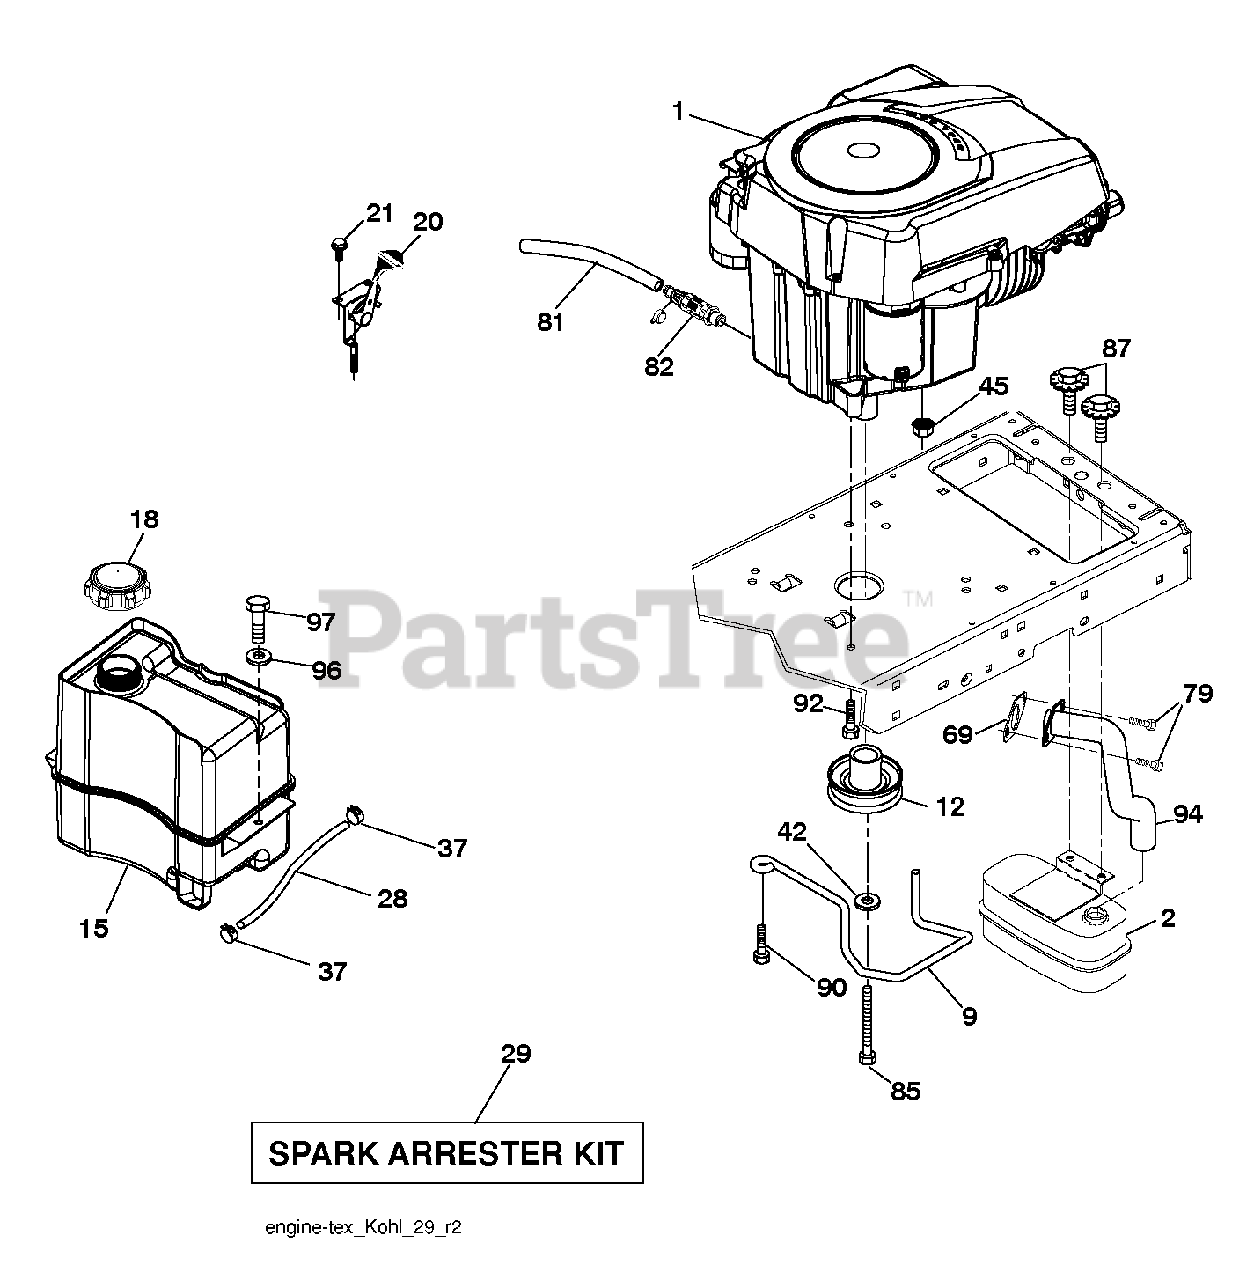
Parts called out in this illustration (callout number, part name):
1	Husqvarna TBD
2	MUFFLER.SINGLE.CYL.KOHL/B&S
9	KEEPER.BELT.ENGINE.4.2
12	PULLEY ENGINE
15	TANK.ASM.FUEL.FR.2.5GA.
18	CAP.2.25'.VENTED.TETHER .EPA
20	CONTROL.TH/CK.COBRA.KO
21	SCREW.#10 X 0.750.BOS
28	LINE.FUEL.20"FRONT.EMI
29	KIT.SPARK ARRESTOR 794945 B&S
37	HOSE CLAMP
42	LOCKWASHER
45	NUT
69	GASKET.EXHAUST.KOHLER
79	SCREW.SOCKET HD.5/16-1
81	TUBE, DRAIN OIL ASM.
82	VALUE.OIL.DRAIN
85	BOLT HEX 7/16-20X4-1/4"
87	Bolt, 5/16-18 X 1-3/4
90	SCREW 3/8-16X1
92	SCREW 3/8-16X1
94	RP.TUBE.EXHAUST.KOHL.COURAGE
97	SCREW HEXWSHR 1/4-20X3/4
